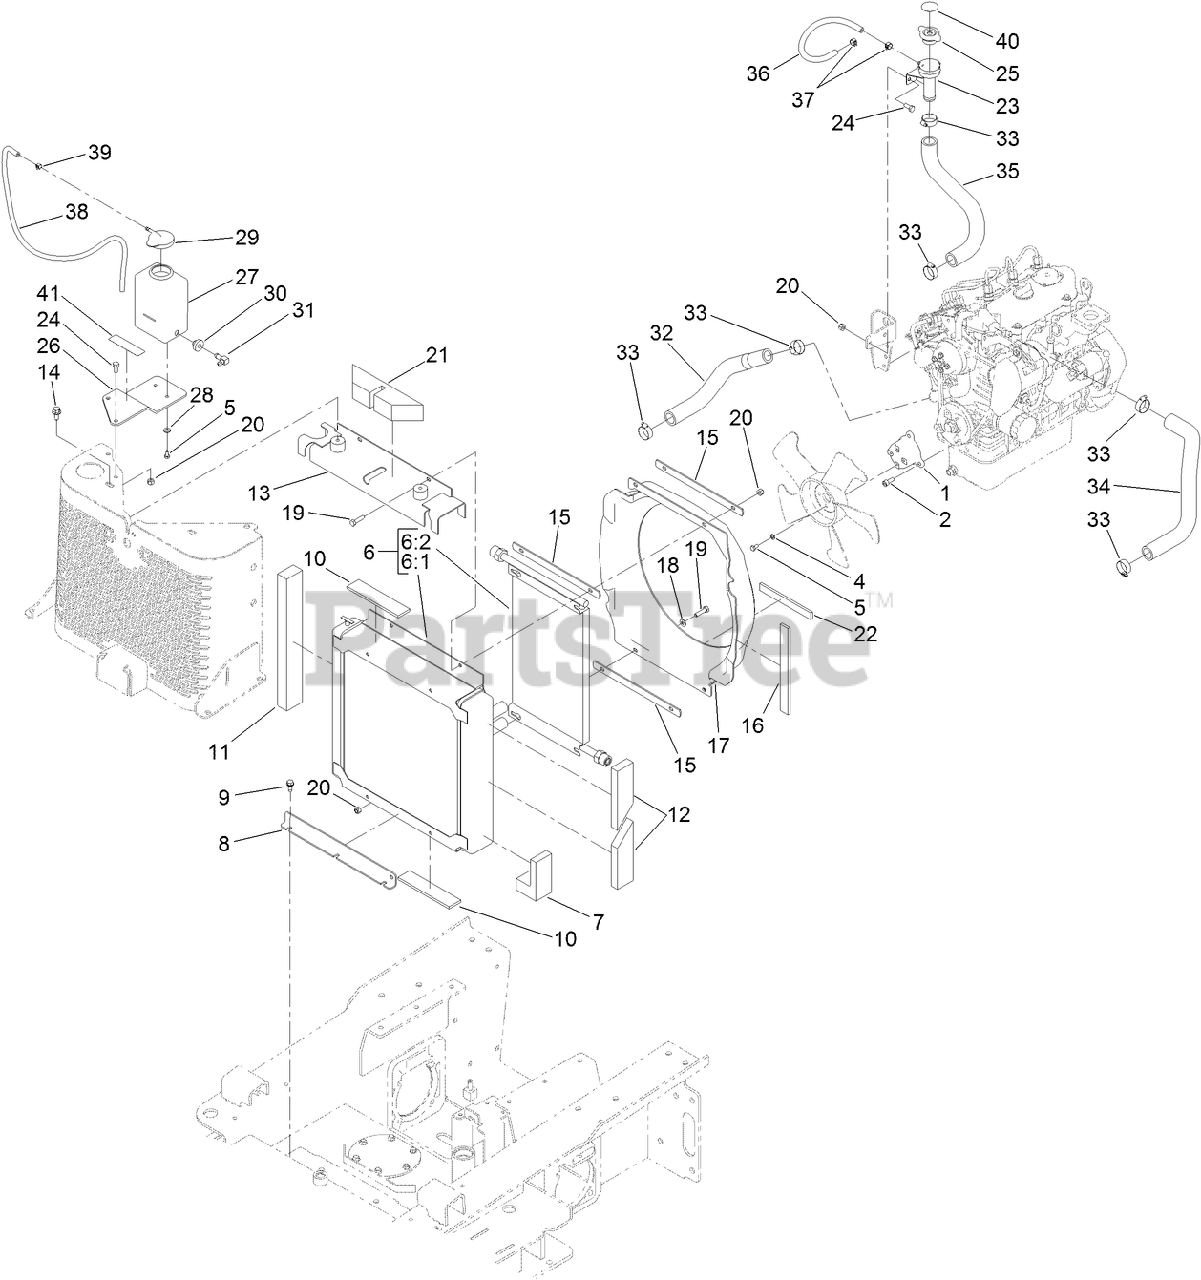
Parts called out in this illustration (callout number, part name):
1	SPACER-MACHINED
2	SCREW-CAP, HSH
4	SCREW-HH
5	SCREW-HH
6	RADIATOR AND OIL COOLER ASM
6:1	RADIATOR
7	SEAL-FOAM
8	MOUNT-RADIATOR
9	SCREW-THD ROLL, HWH
10	PAD-RUBBER
11	SEAL-FOAM
12	SEAL-FOAM
13	BRACKET-RADIATOR
14	SCREW-HHF
15	PLATE-BACKING
16	FOAM-SEAL
17	SHROUD-FAN
18	WASHER-PLAIN
19	SCREW-HH
20	NUT-LOCK, NI
21	SEAL-FOAM
22	PAD-RUBBER
23	TUBE-FILLER, RADIATOR
24	SCREW-HH
25	CAP-RADIATOR
26	BRACKET-TANK, OVERFLOW
27	TANK-OVERFLOW
28	WASHER-FLAT
29	CAP-TANK, OVERFLOW
30	BUSHING
31	FITTING-ELBOW, 90 DEG
32	HOSE-RADIATOR
33	CLAMP-HOSE
34	HOSE-RADIATOR, LOWER
35	HOSE-RADIATOR
36	HOSE-LP
37	CLAMP-HOSE
38	HOSE-LP
39	CLAMP-HOSE
40	DECAL-CAP, RADIATOR
41	DECAL-RADIATOR FILL
